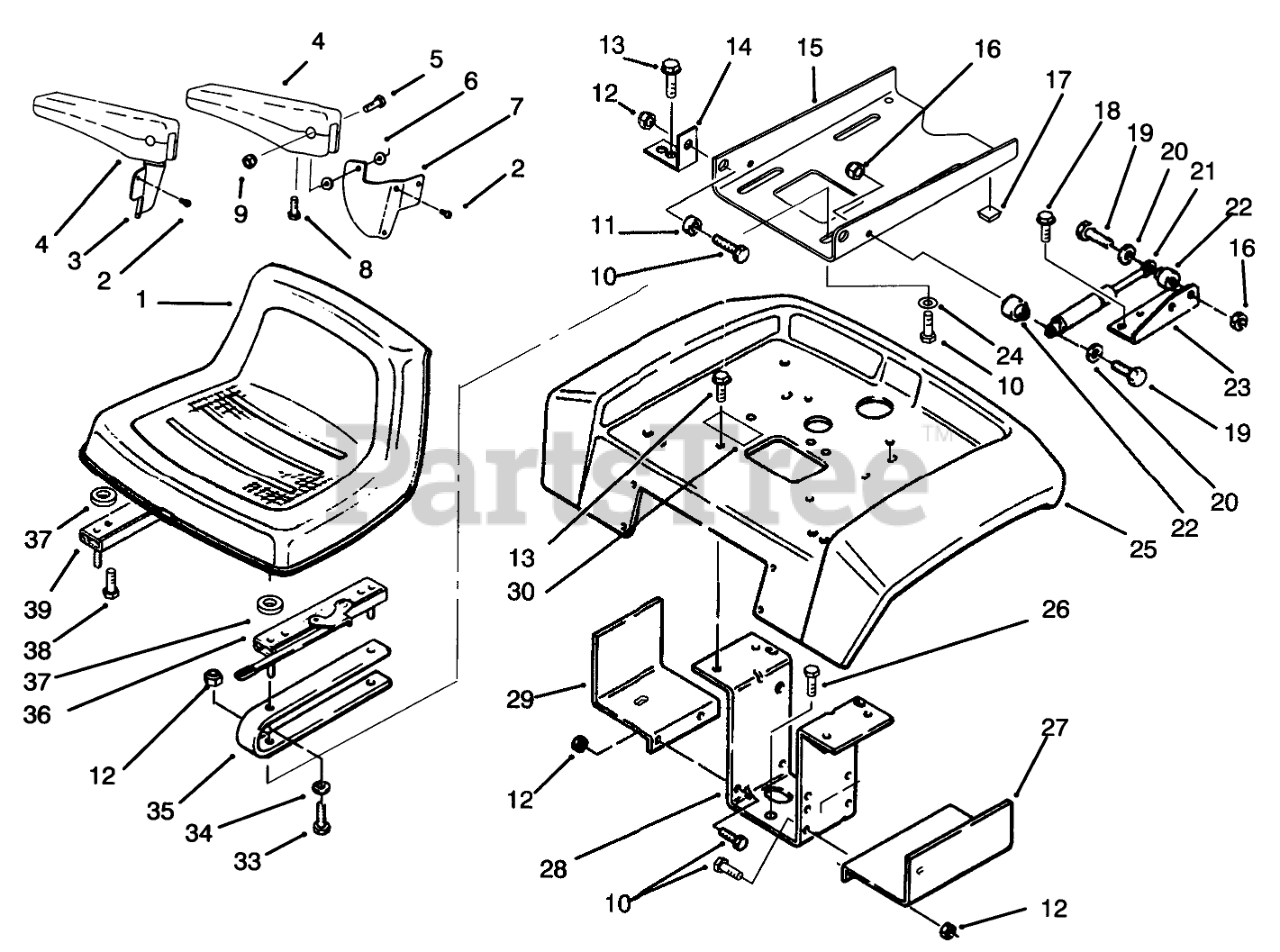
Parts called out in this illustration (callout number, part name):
1	Seat
2	3/8-16 X 5/8 SCREW
3	RH ARM BRACKET
4	ARMREST
5	3/8-16X1-1/2 SCREW
6	NYLON SPACER
7	LH ARM BRACKET
8	3/8-16 X 3/4 SCREW
9	3/8-16 ACORN LOCKNUT
10	SCREW-HH
11	BUSHING
12	NUT-LOCK, NI
13	Bolt
14	BRACKET-PIVOT
15	Plate-SeatPivot
16	NUT-LOCK, NI
17	BUMPER SJ5514 BLACK
18	Bolt
19	SCREW-HH
20	WASHER-FLAT
21	GAS SPRING
22	SPACER
23	BRACKET-CYLINDER R
24	WASHER-PLAIN
25	Fender
26	SCREW-HH
27	Fuel Tank Support LH
28	Bracket-Fender
29	Support-FueITank RH
30	DECAL-DO NOT TOW
33	SCREW-HH
34	WASHER-LOCK
35	Seat Spring
36	Adjuster-Seat
37	SPACER-NYLON
39	ADJUSTER-R.H. SEAT
